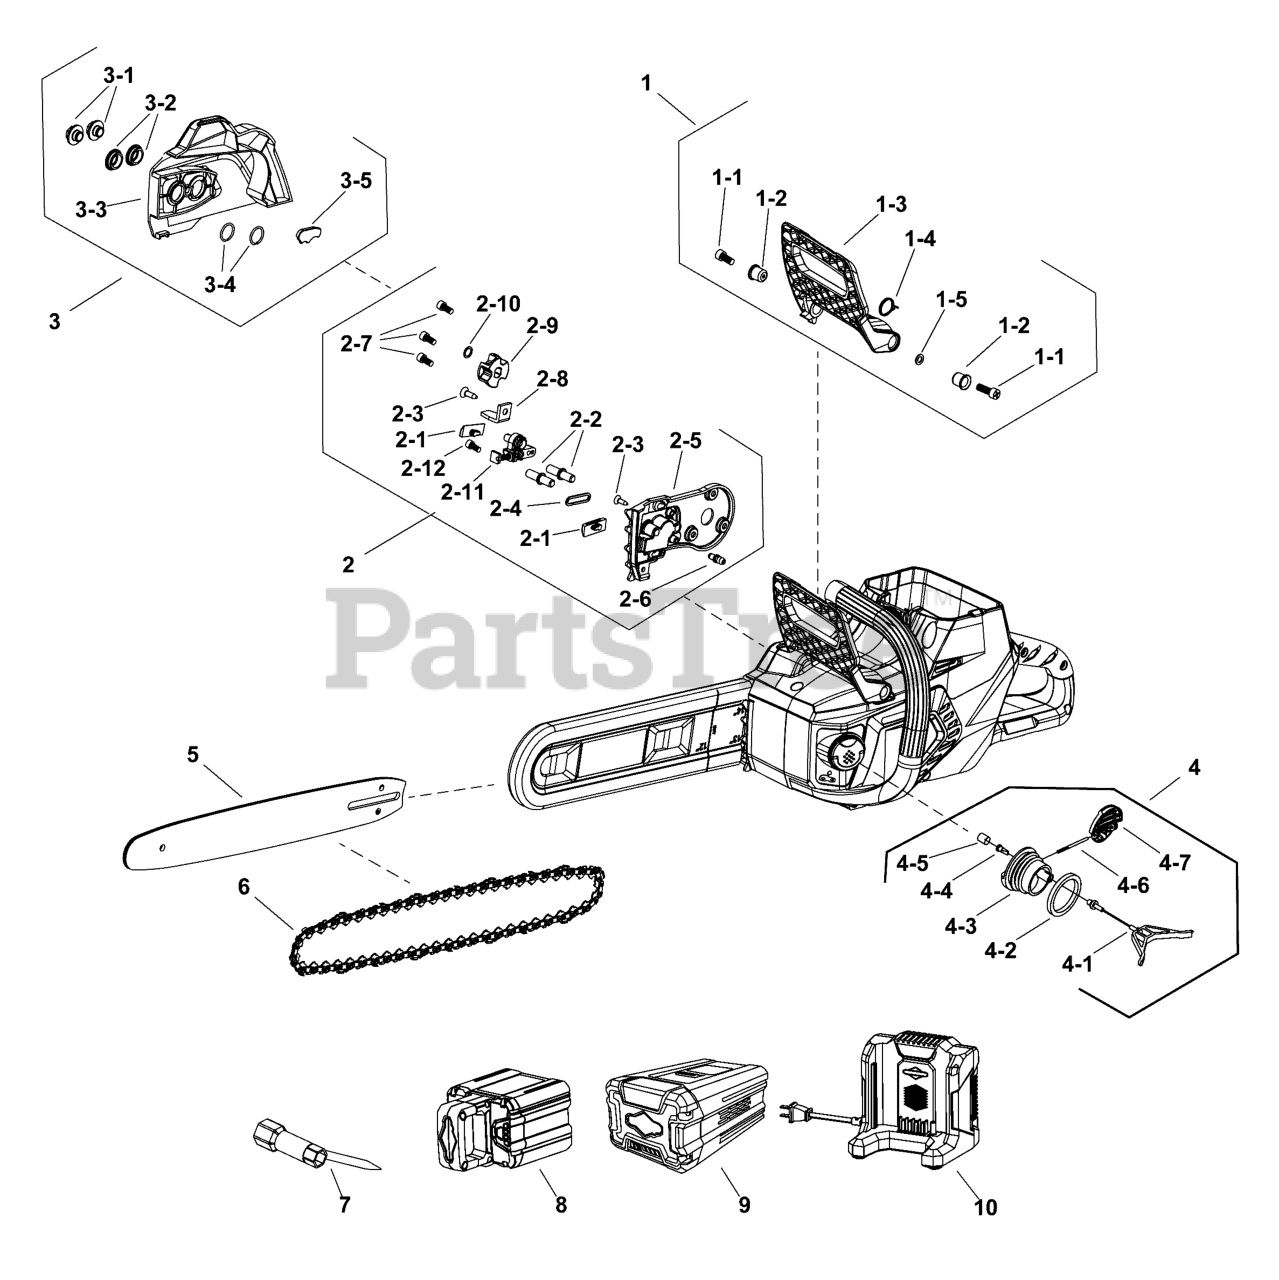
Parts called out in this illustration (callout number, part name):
1	Kit, Guard
1-2	BUSHING
1-3	GUARD
1-4	SPRING, Torsion
1-5	WASHER, Plain
2	KIT, Chain Tension
2-1	GASKET, Splash Guard
2-2	STUD
2-4	SEAL, Oil
2-5	BRACKET, Bar
2-6	GROMMET, Oil
2-8	RETAINER, Chain
2-9	SPROCKET
2-10	CIRCLIP
2-11	TENSIONER, Chain
3	KIT, Side Panel
3-2	SLEEVE
3-3	PANEL, Side
3-4	RING, Snap
3-5	GASKET, oil
4	KIT, Oil Cap
4-1	HANDLE
4-2	SEAL
4-3	KNOB, Oil
4-4	VALVE, Air
4-6	PIN
4-7	CAP, OIl
5	KIT, Bar, 14", (TriLink M1431452-1041)
6	KIT, Chain, 14", TRiLink CL14352
7	KIT, Tool
8	* BATTERY, 2.0, 48V
9	* BATTERY, 5.0, 48V
10	* BATTERY CHARGER, 48V
